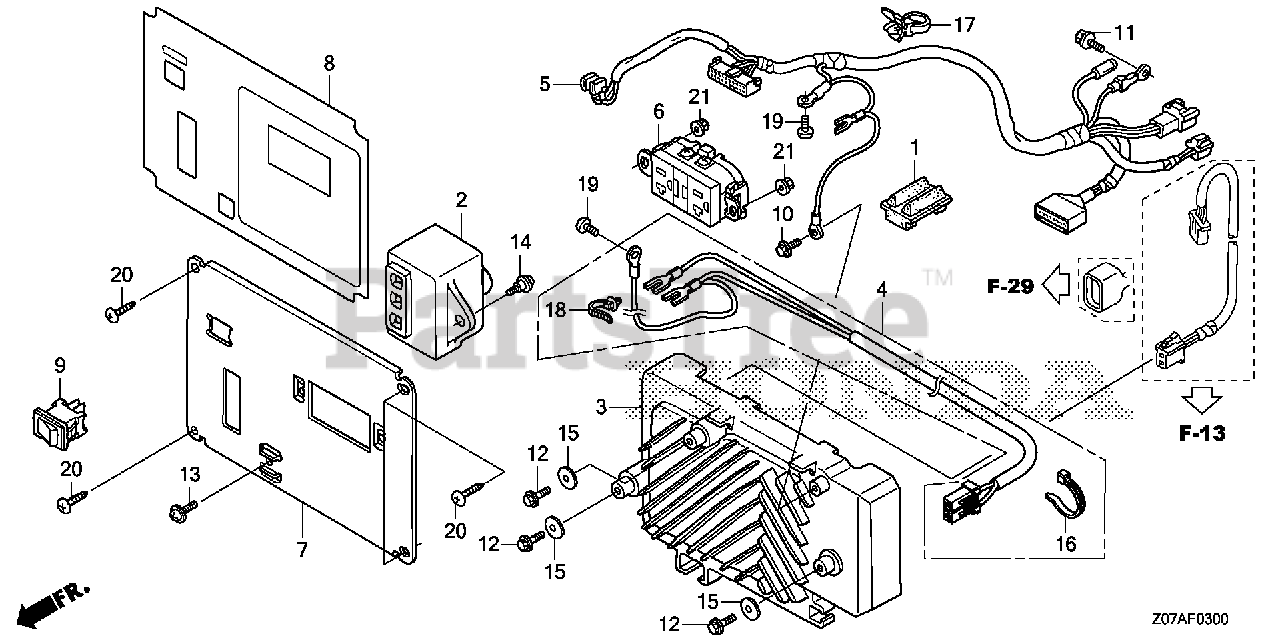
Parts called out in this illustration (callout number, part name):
1	RUBBER B, TANK MOUNTING
2	SPARK UNIT
3	INVERTER UNIT
4	SUB-WIRE HARNESS ASSY. (EB-A)
5	WIRE HARNESS ASSY., CONTROL
6	RECEPTACLE (20A-125V) (GFCI)
7	PANEL, CONTROL (EB-A)
8	MARK, CONTROL PANEL (EB-A)
9	SWITCH, AUTO-THROTTLE
10	BOLT, FLANGE (5X10)
11	BOLT, FLANGE (5X10)
12	BOLT, FLANGE (5X12)
13	SCREW, PAN (5X12)
14	SCREW, PAN (5X13)
15	WASHER, PLAIN (20MM)
16	BAND, WIRE HARNESS
17	BAND (100MM) (BLACK)
18	CLIP, HARNESS BAND (145MM) (BLACK)
19	SCREW, PAN (5X8)
20	SCREW, TAPPING (5X16) (PO)
21	NUT, FLANGE (4MM)
